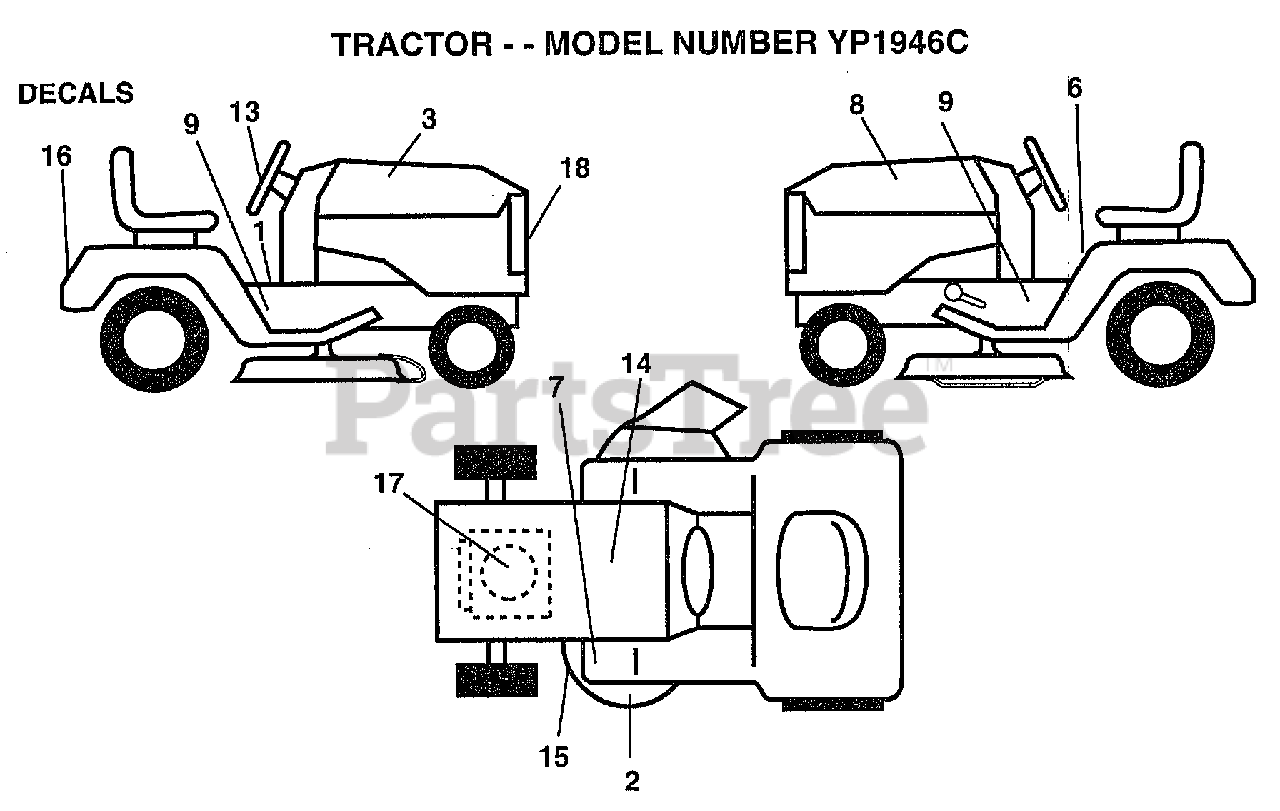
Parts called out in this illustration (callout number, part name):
1	"DECAL.OPER,SDL"
2	"DECAL, WARNING"
3	"DECAL HOOD,RH 19H"
6	DECAL.CAUT.ENG/FR
7	DECAL T
8	"DECAL HOOD,LH 19H"
9	"DECAL CHASSIS,46"""
13	DECAL INS STRG WH
14	DECAL.BATRY.3-3908
16	DECAL FENDER
